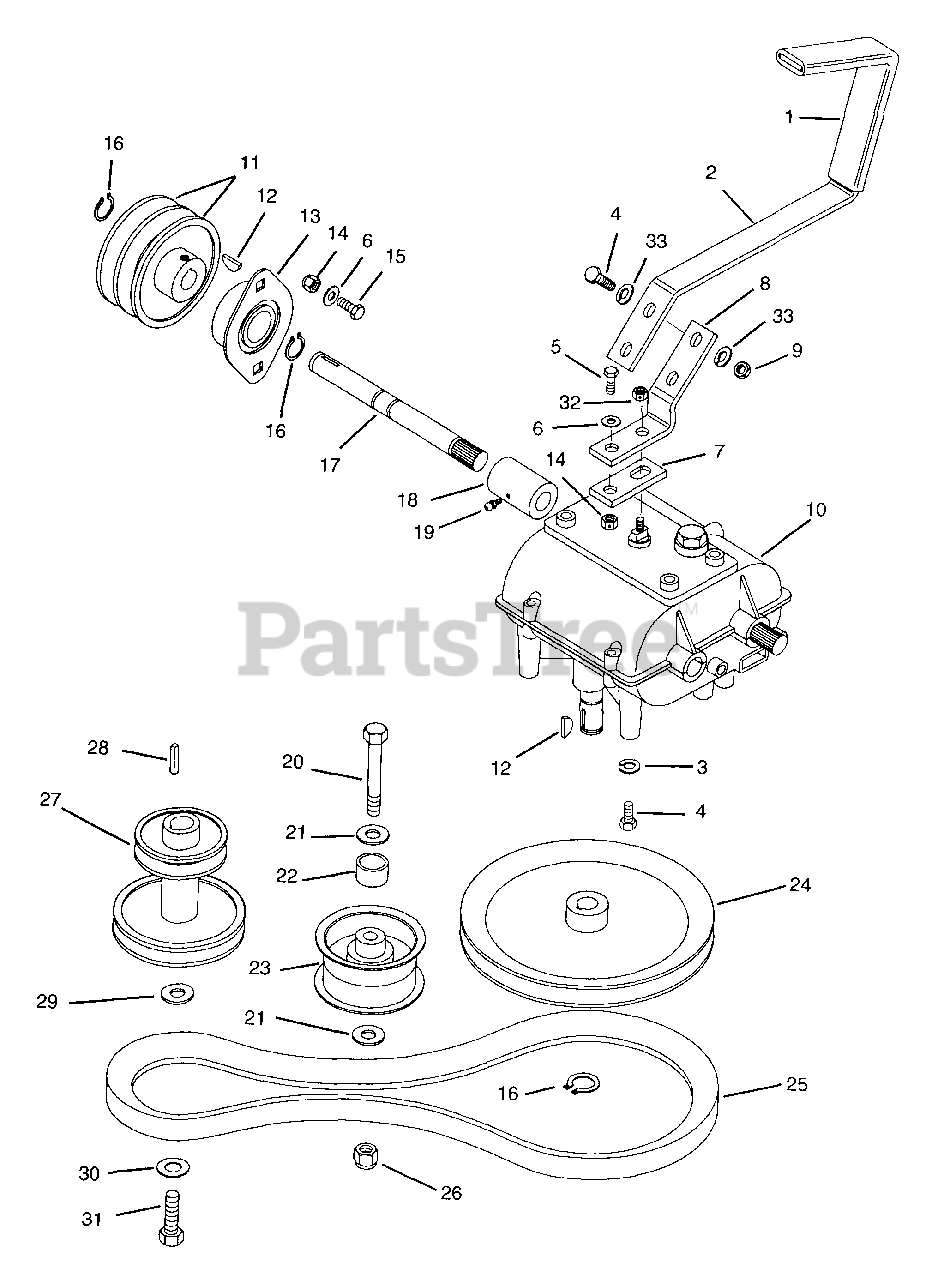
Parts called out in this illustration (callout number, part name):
1	GRIP - HANDLEBAR
2	LVR,TRANS SHIFT
3	@WSHR-LK .31X.078 REG YWZC
4	@BLT-HEX .31-18X1.00 GR5 YWZC
5	@BLT-HEX .25-20X1.00 GR5 YWZC
6	@WSHR-FL-STL.281X.62X.065 YWZC
7	PLATE, SHIFT
8	ARM, SHIFT
9	@NUT-LK-CTR .31-18 YWZC
10	TRANSMISSION
11	KIT-DRIVE SHEAVE
12	KEY-WDRF .19X.75 HRD #9
13	BRG-FLG .625X1.875X.797
14	@NUT-LK-CTR .25-20 YWZC
15	@BLT-HEX .25-20X.75 GR5 YWZC
16	RG-RTNG-EXT .579X.035
17	SHAFT, HALF
19	FTG,LUBE, .25-28 SELF THREAD
20	@BLT-HEX .38-16X2.25 GR5 YWZC
21	@WSHR-FL-STL.406X.812X.065 YWZ
22	SPACER .625X.385X.55
23	IDLER-PLY FLAT 3.25 X .38 X1.0
24	PLY-V 7.50X.626
25	V-BELT, HA-RAW EDGE
26	@NUT-LK-CTR .38-16 YWZC
27	CRANK SHEAVE-PRO
28	KEY-SQ .248X2.38
29	WSHR-LK .44X.109 REG YWZC
30	WSHR-FL-STL .469X2.00X.25 YWZC
31	BLT-HEX M10 X 1.5X60 8.8 YWZC
32	NUT-LK-CTR .375-24 YWZC
33	@WSHR-FL-STL.344X.688X.065YWZC
